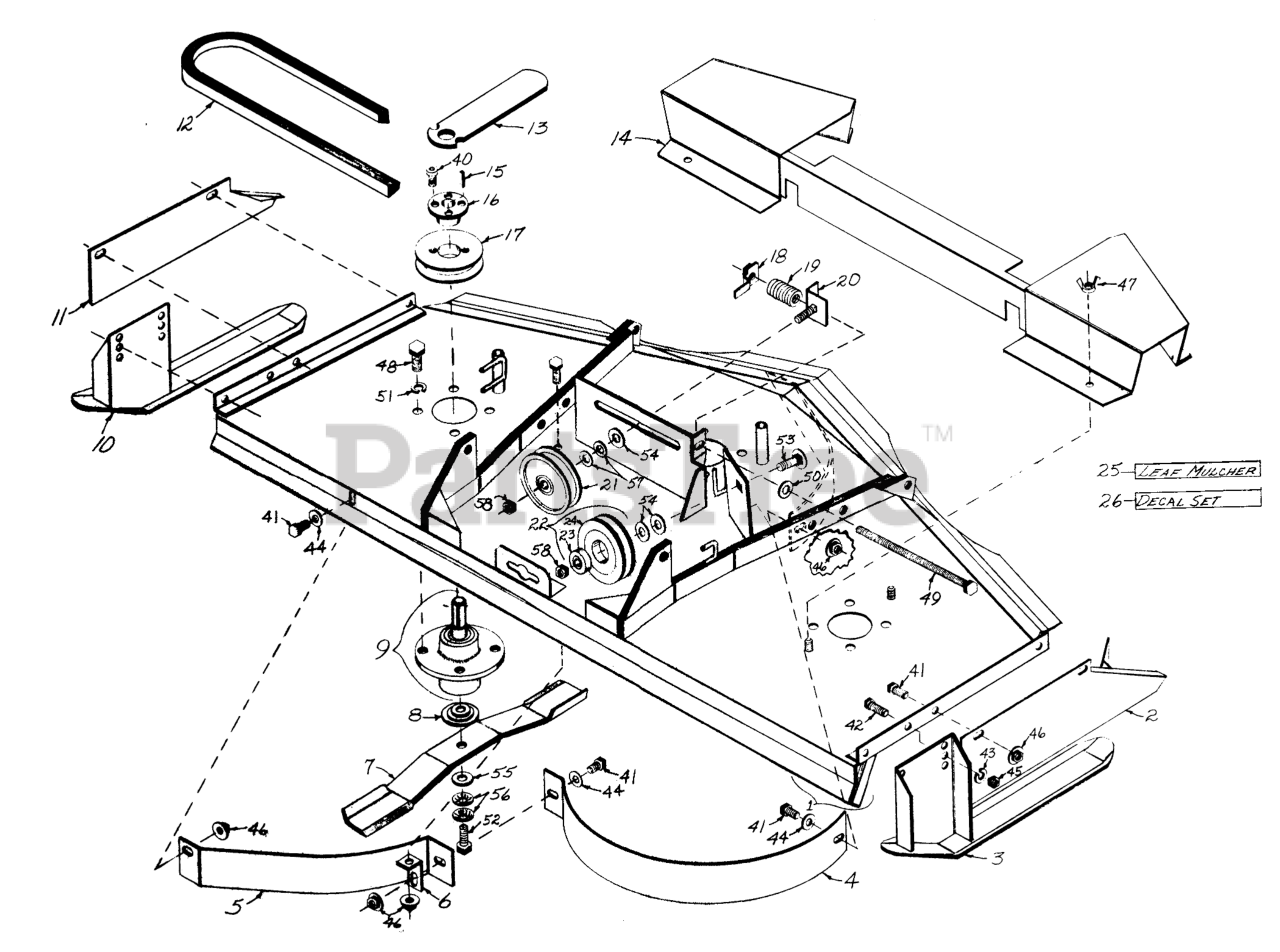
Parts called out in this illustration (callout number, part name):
1	Frame Only
2	Left Side Shield
3	Blade Bar
4	Center Front Baffle
5	Right Front Baffle
6	Baffle Mounting Lug
7	Blade
8	Twill Guard
10	Right Side Skid
11	Right Side Shield
12	V BELT
13	Spindle Lock Wrench
14	Tire 4.00 x 8
15	Attaching Bracket
16	Push Rod
17	Sheave 3.9 PD
18	Right Hand Grass Deflector
19	Ledger Plate
20	Idler Takeup Bolt and Clip
21	4 7/16 OD Flat Idler Pulley
22	Spring
23	U Bolt
24	4 1/2 OD V-ldler Sheave Less Bearing
26	DECAL SET
40	1/4 NC x 3/4 Socket Head Cap Screw
41	Bolt 3/8-16 x 3/4
42	Bolt 3/8-16 x 1
43	Lockwasher
44	Washer
46	Nut, Jam, 3/8-24 Thd
47	3/8 NC Wing Nut
48	1/2 NF x 1 Hex Head Cap Screw
49	Tube 5.00 x 8
50	Washer
51	Lockwasher
52	Safety Pin
53	5/8 NC x 2 Carriage Bolt
54	Washer, 5/8
55	5/8 Standard Flat Washer
56	5/8 Cup Washer
57	Shovel Support, Straight
58	3/8-16 E.S.
